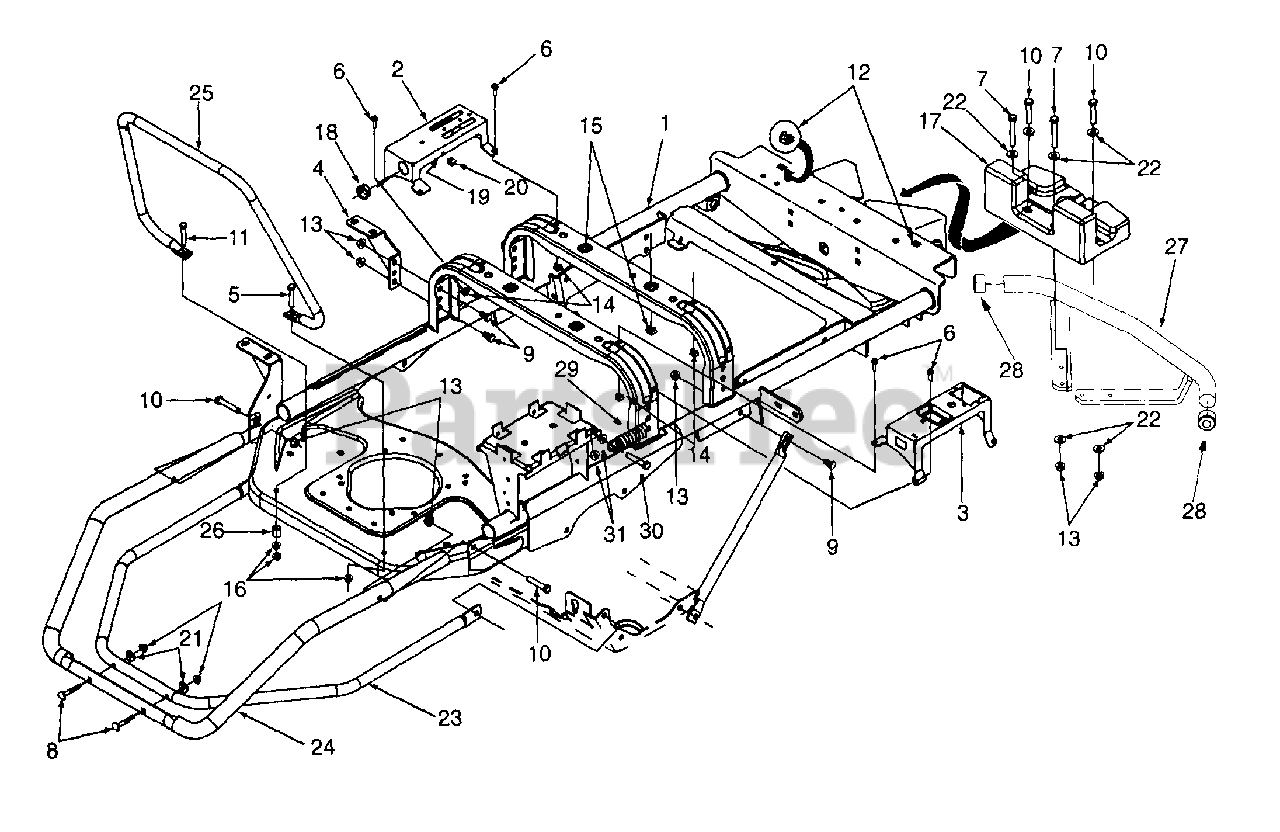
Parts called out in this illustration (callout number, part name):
6	Hex Washer Screw 1/4-20 x .625
7	Hex Cap Screw
8	Curved Carriage Screw 5/16-18 x 2.0
9	Hex Cap Screw 3/8-16 x 3/4
10	Hex Cap Screw 3/8-16 x 2.5
11	Hex Cap Screw 5/16-18 x 1.75
12	Retainer Nut 3/8-16
13	Hex Flange Lock Nut 3/8-16
14	Retainer Nut 1/4-20
15	Retainer Nut 3/8-16
16	Hex Flange Lock Nut 5/16-18
20	Spring Clip
21	Saddle Washer
22	Flat Washer .406 ID x .875 OD
